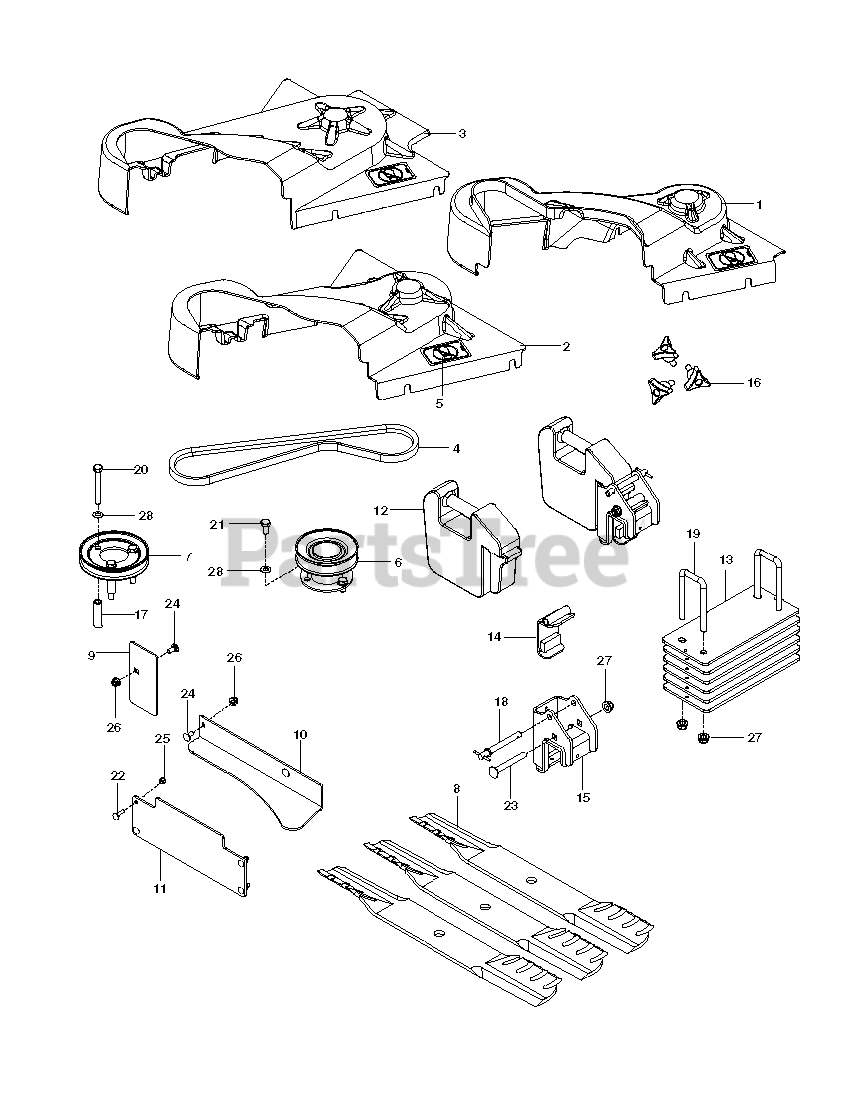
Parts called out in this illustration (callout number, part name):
1	SHEILD BELT BLOWER 48 BLK
2	SHIELD, LOWER, 54"
3	SHIELD, LOWER, 60"
4	BELT.BLOWER
5	DECAL, NO STEP
6	PULLEY.DRIVE.48"
7	PULLEY, DRIVE, 54"
8	BLADE, 19" GATOR, 1.25" LIFT
9	PLATE BLOCK OFF
10	BAFFLE, RH, BLACK
11	BAFFLE, LH, BLACK
12	FRONT WEIGHT CAST PZ DFS
13	PLATE.WEIGHT.BLK.X431
14	LATCH, WELDMENT
15	BRACKET, WEIGHT, BLK
16	KNOB W/STUD
17	SPACER, PULLEY
18	PIN, DETENT
19	LINKAGE, U-BOLT
20	HCS 5/16-18 X 5/8 GR 5 ZD
21	HCS 5/16-18 X 5/8 GR 5 ZD
22	RHSNB, 1/4-20 X 1, GR5
23	RHSNB 1/2-13 X 4 GR 5 ZD
24	BOLT 5/16C X 3/4" CARRIAGE
25	NUT.1/4-20.HEX.NYLOC.ZD
26	5/16-18 NYLOC FLANGE NUT
27	NUT, 1/2-13 HEX FLG NYLOC ZD
28	WASH 5/16 DISC SPRING ZD
